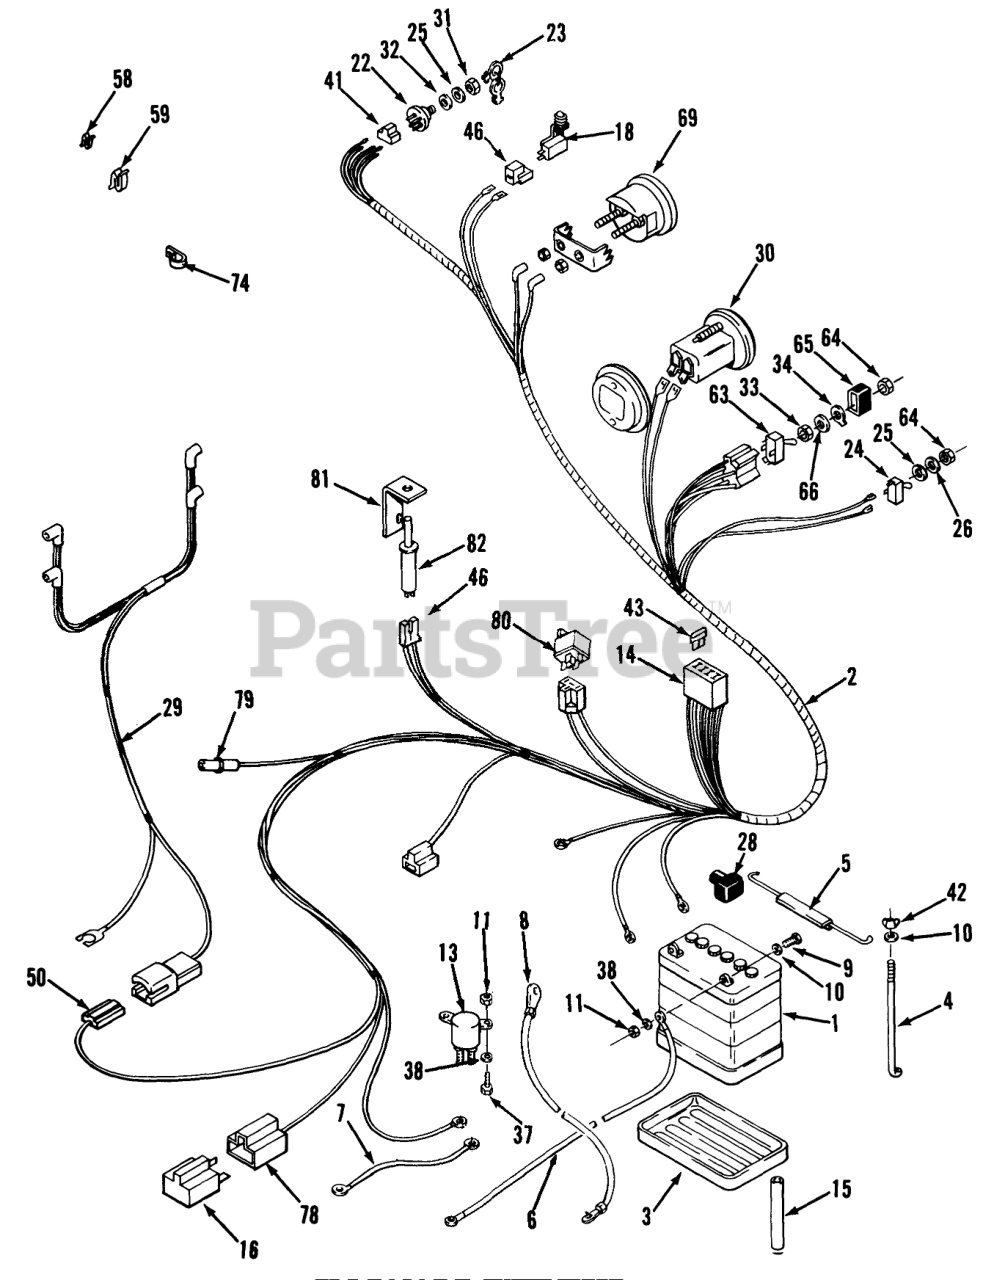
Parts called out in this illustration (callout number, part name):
1	Battery
2	MAIN-HARNESS & DIA
3	TRAY-BATTERY
5	ROD-BATTERY HOLD DWN
6	WIRE - 14" BLACK
7	ASS'Y-WIRE 9.0"
8	WIRE - 14" BLACK
9	Bolt
11	Nut
13	Solenoid (Includes two of item 11)
14	FUSE-HOLDER 4 WAY
15	TUBE-BATTERY DRAIN
16	DIODE-ASS'Y
18	Seat Switch
22	Ignition Switch (Includes items 31 & 32)
23	Ignition Key
24	Light Switch (Includes items 33 & 34)
25	Washer
26	Washer
28	Boot
29	HARNESS-HEADLIGHT
30	Hourmeter (Includes 114017 Bracket, 915962 Keps Nut (2) & 5924 E.S. Nut #10-24 (2))
32	LOCKWASHER
33	NUT-HEX, SPECIAL
34	TAB-WASHER
37	Screw
38	Washer
41	CONNECTOR-5 WAY-SERV
42	Nut
43	FUSE-BLADE, 15 AMP
46	CONNECTOR BODY
50	CONNECTOR BODY ELECT
58	CLIP
59	SPEED CLIP
63	Electric Clutch Switch (Includes items 33, 34 & 64)
65	COVER-PTO SWITCH
66	WASHER
69	Voltmeter (Includes 109650 Clamp & 5924 #10-32 Nut (2))
74	CLAMP
78	CONNECTOR 5 WAY
79	Connector-Socket
80	RELAY
81	Bracket
82	SWITCH-PLUNGER
